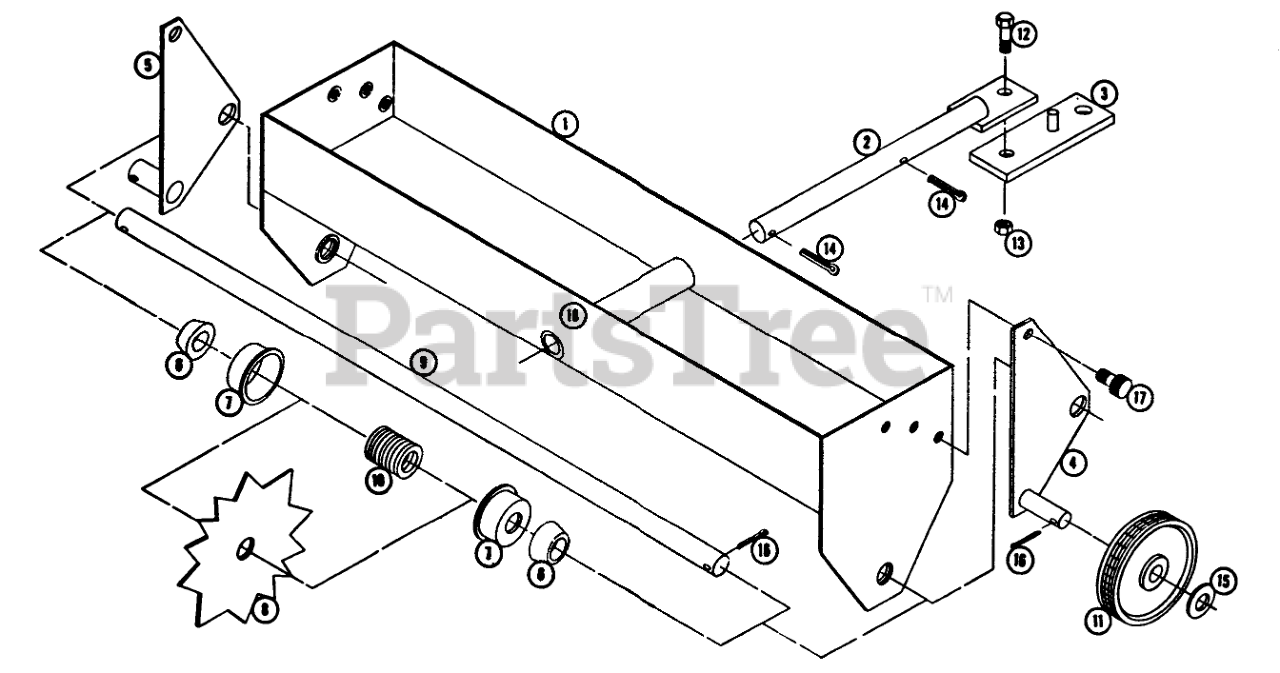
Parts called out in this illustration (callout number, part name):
1	Frame & Box Assy.
2	Hitch Bar Assy.
3	Pivot Bar
4	Wheel Support Assy. R.H.
5	Wheel Support Assy. L.H.
6	Spacer-Outer
7	Cup Spacer
8	Spike
9	Axle
10	Spring
11	Wheel
12	Bolt Hex 1/4-20 x 1 1/4
13	Locknut-1/2-13
14	SPIROL ROLL PIN
15	Washer
16	Cotterpin 3/16 x 1 1/2
17	Thumb Screw
18	Decal
